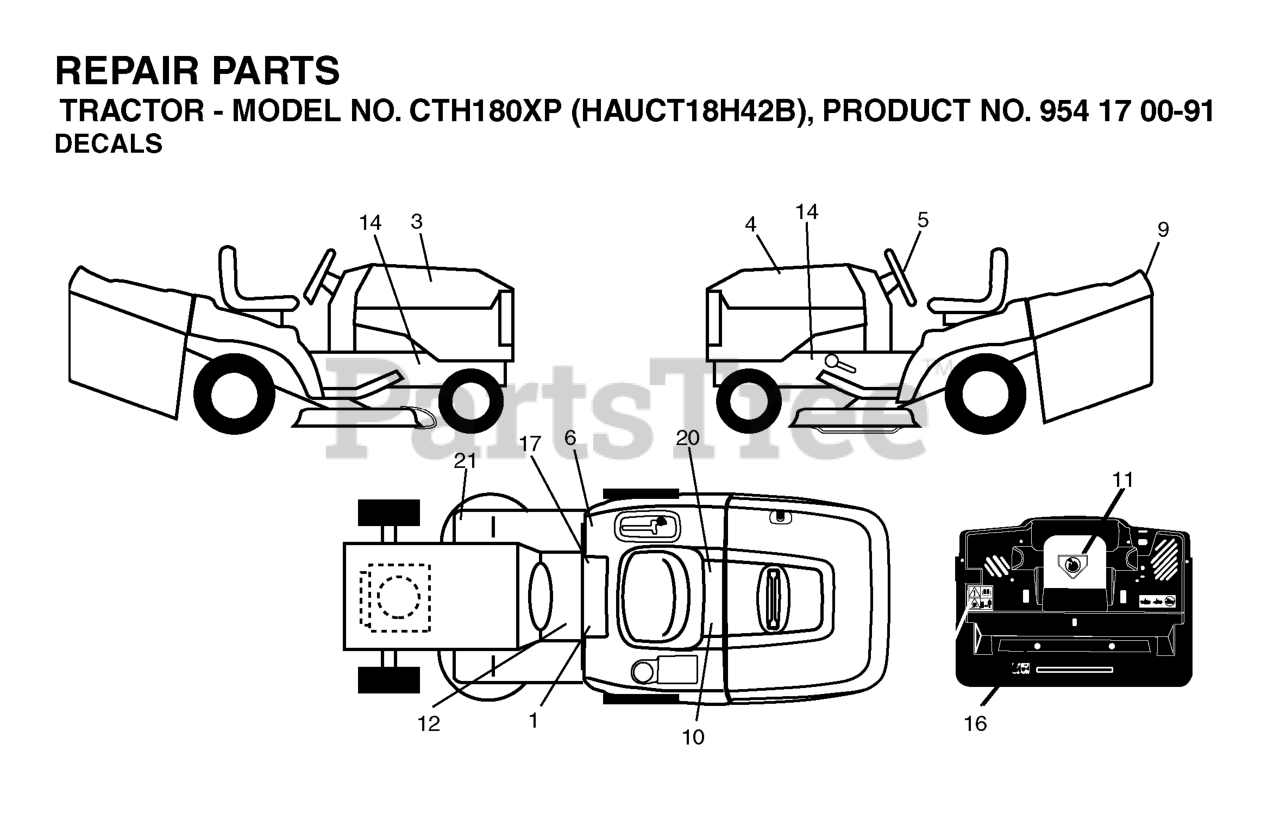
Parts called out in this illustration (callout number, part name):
1	DECAL READ OWNER'S MAN SYMS
5	DECAL.WHEEL.STEERING.HUSQ.PERM
6	DECAL
9	DECAL FENDER HUSQ
10	DECAL BTRY SYMBOLS
11	DECAL.INTERNATIONL.CUTFINGER
12	DECAL
16	DECAL
17	DECAL PARK BRAKE
20	DECAL.BYPASS.FENDER.CRD.LT.YT
